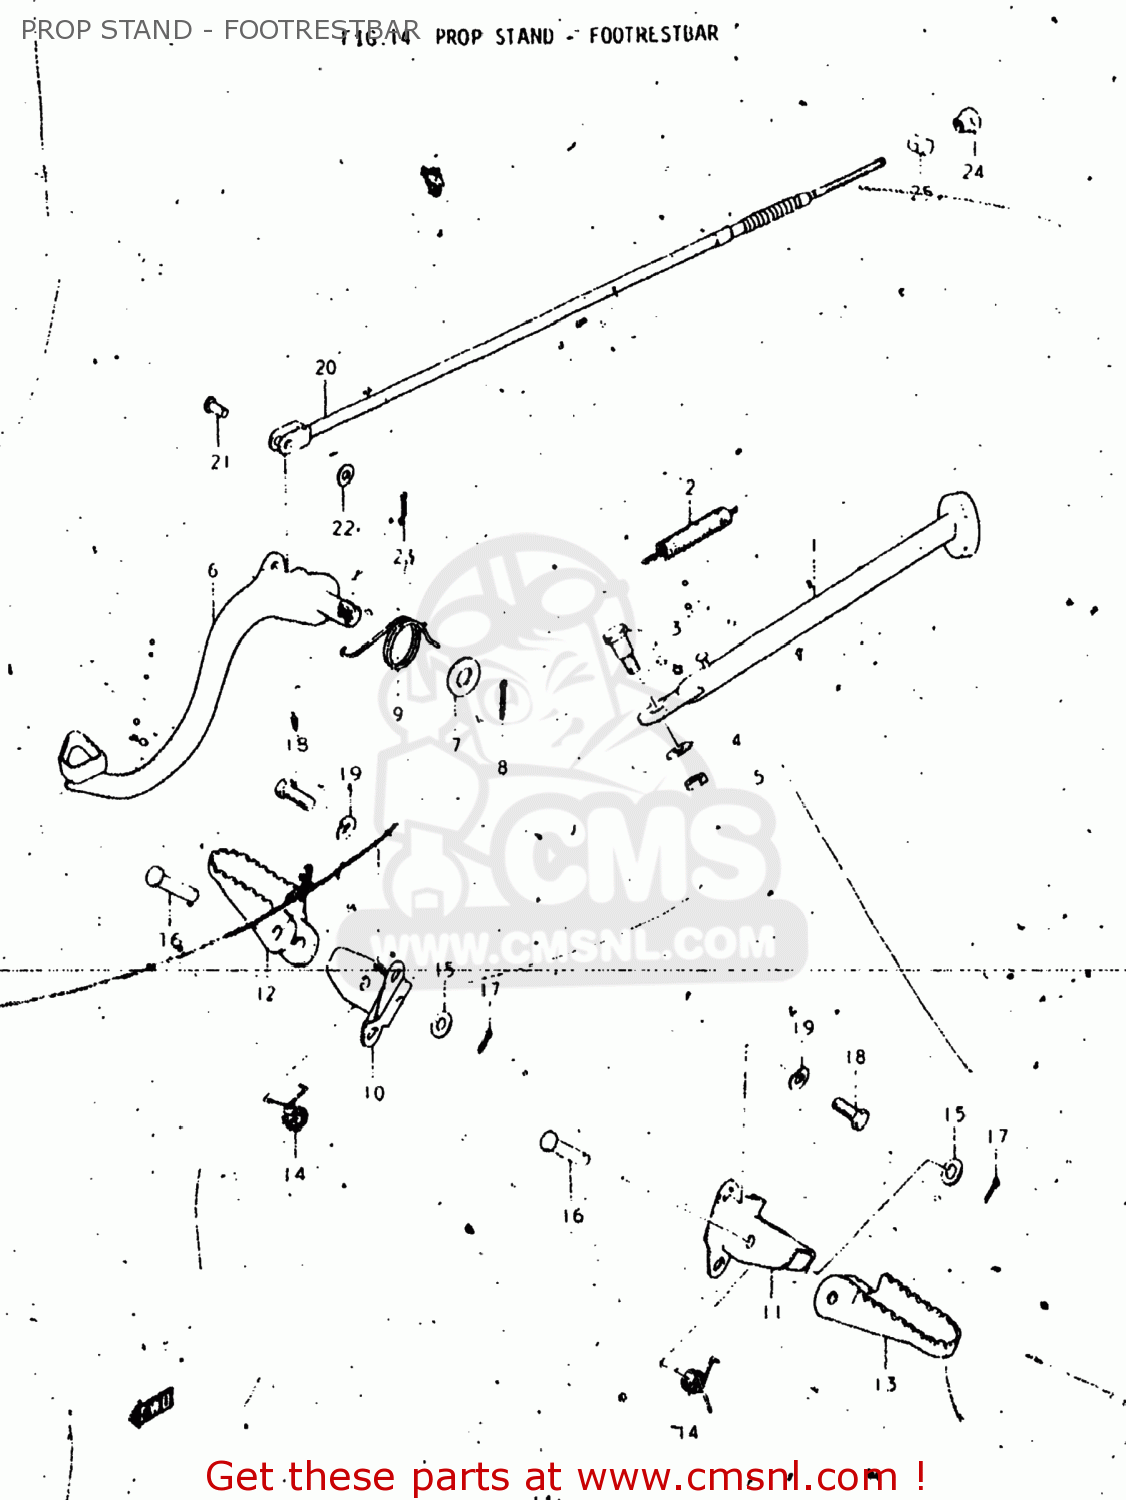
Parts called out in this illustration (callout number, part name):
1	STAND,SIDE
2	SPRING
3	BOLT(10X30)
4	WASHER
5	NUT
6	PEDAL,BRAKE
7	WASHER
8	PIN 30X20
9	SPRING
10	BAR,FRONT FOOTREST
11	BAR,FRONT FOOTREST,LEFT
12	RUBBER,FOOTREST
13	FOOTREST
14	SPRING
15	WASHER
16	PIN
17	PIN 20X20
18	BOLT
19	LOCK WASHER
20	CABLE,RR BRAKE
21	PIN(L:17.5)
22	WASHER
23	PIN
24	NUT
25	PIN(11X18)
